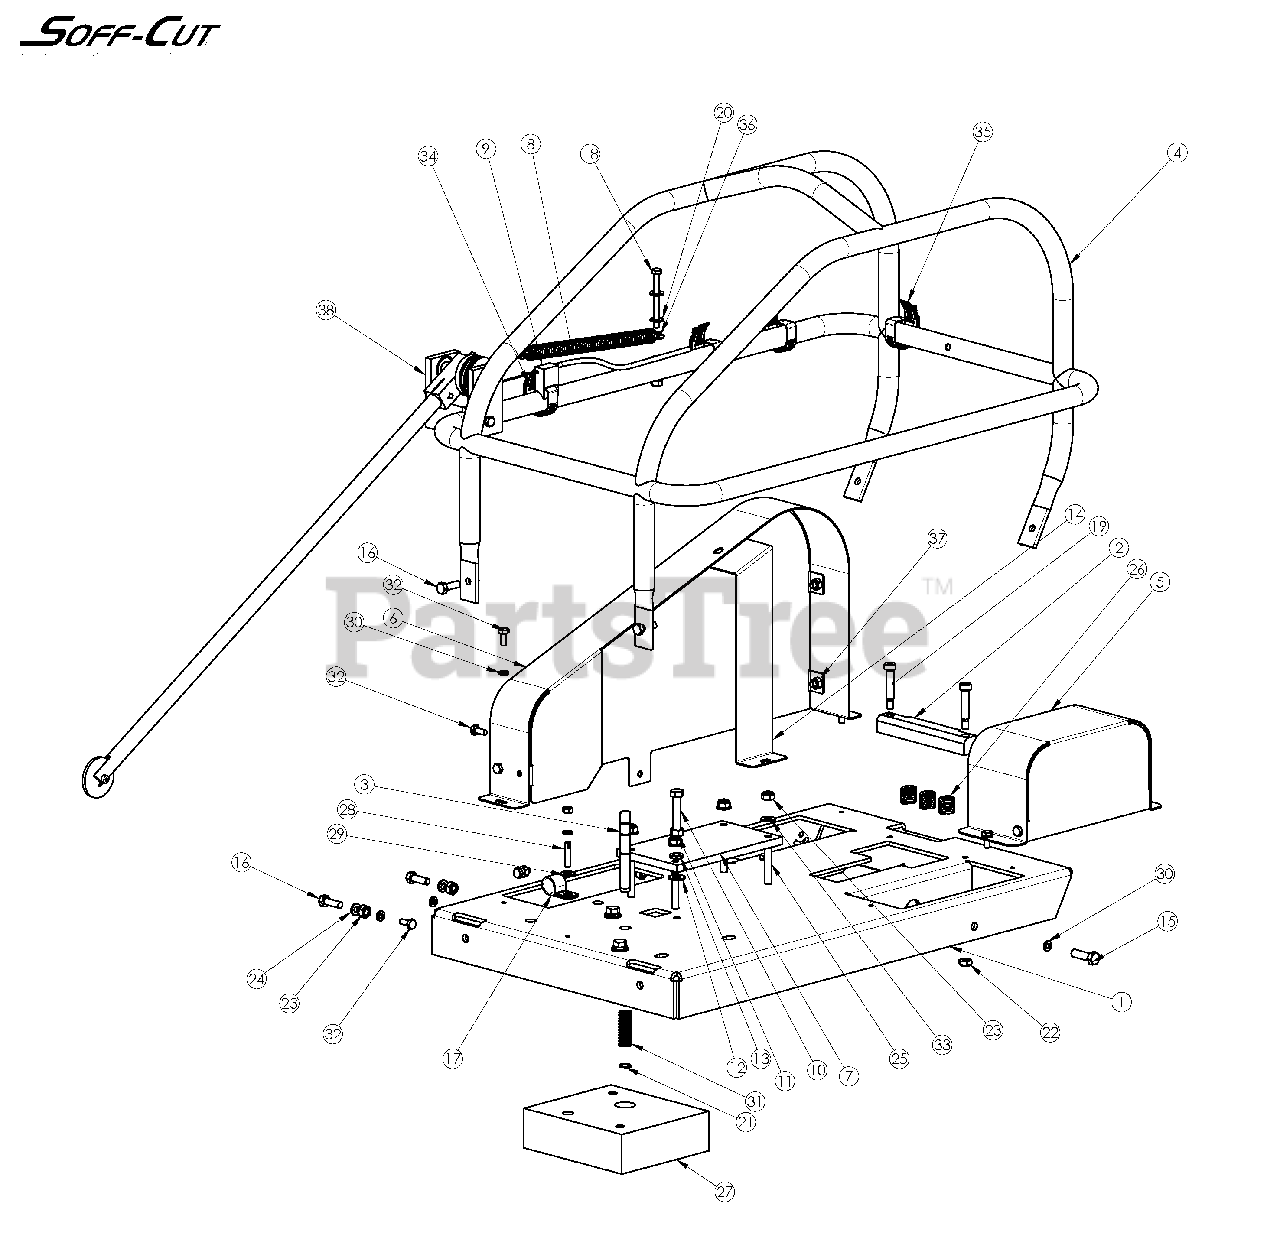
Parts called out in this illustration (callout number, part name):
10	HEX BOLT 3/8-16X2 FULL THREAD
12	FLAT WASH 3/8 STL CAD
15	HEX BOLT 3/8-16X1 1/4 CAD GR 5
16	HEX BOLT 5/16-18-1 CAD GR 5
23	NYLOC NUT 5/16-18 CAD PL.
29	FLAT WASH 1/4 PFC9 SAE ZINC
37	NYLOC NUT 1/4-20 CAD PL.
